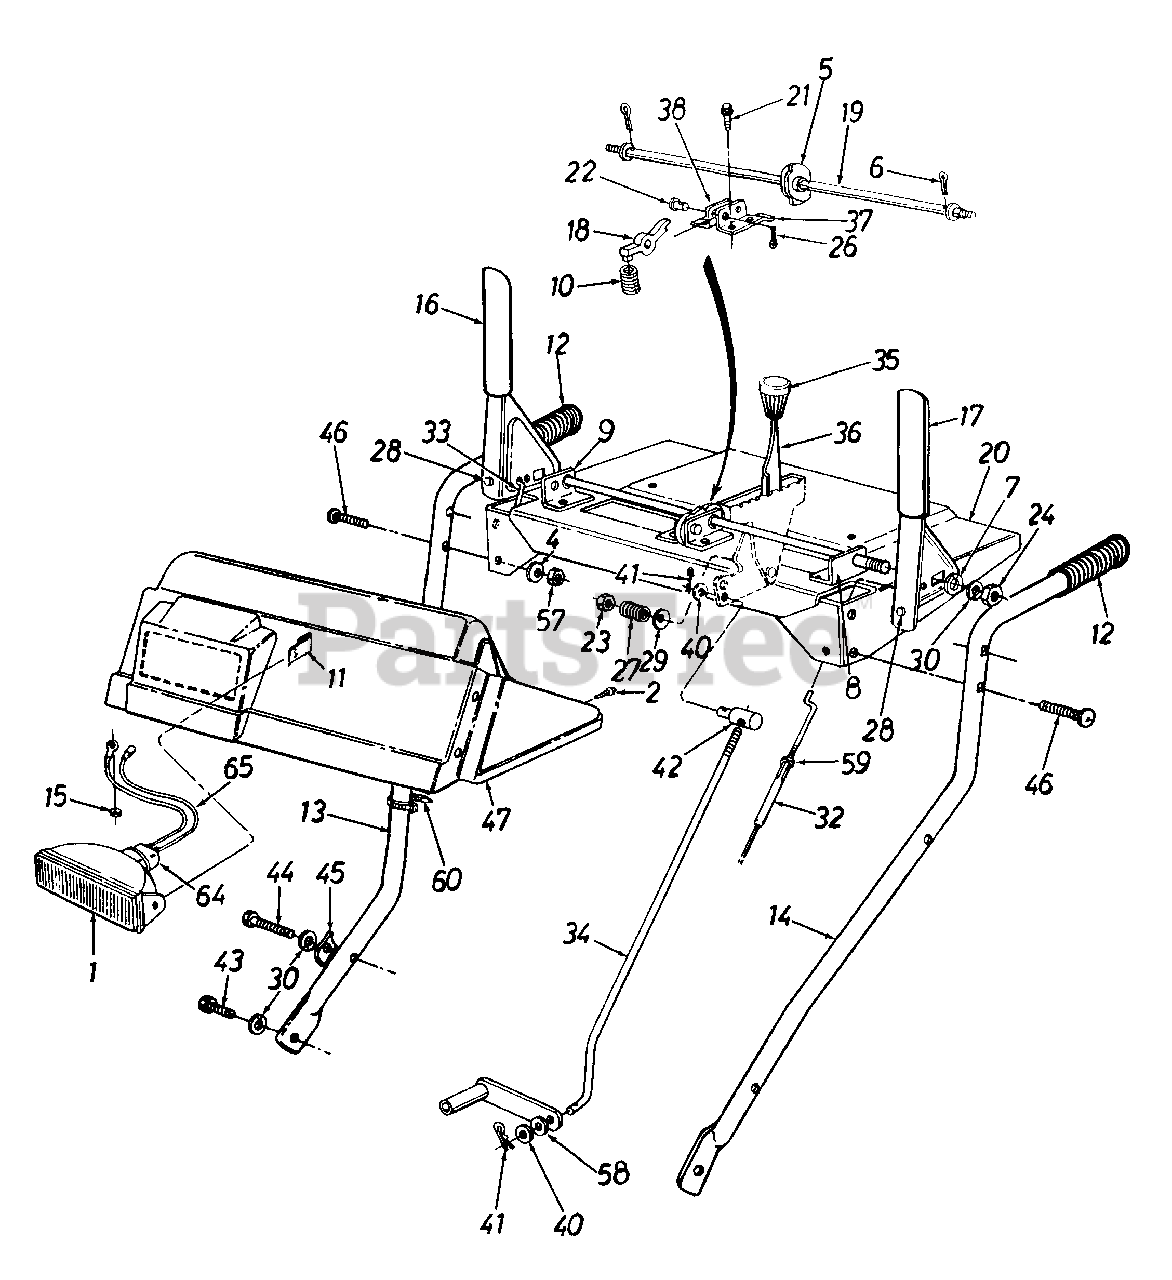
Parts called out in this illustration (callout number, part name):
1	Lamp Housing w/Lens
2	Truss Mach. B-Tap Scr. #10 x .5
4	BELL-Wash .325" I.D. x .88" O.D.
5	Cam Handle Lock
6	Cotter Pin 3/32" Dia. x .75" Lg.
7	Washer (Special) .72" O.D.
10	Compression Spring
11	Retaining Clip
13	Handle - R.H.
14	Handle - L.H.
15	Hex Sems Nut 1/4-20 Thd.
16	Engagement Handle - R.H.
17	Engagement Handle - L.H.
18	Pawl Handle Lock
19	Rod Cam
22	Clevis Pin .437" Dia. x .65" Lg.
23	Hex Ins. L-Nut 3/8-24 Thd.
24	Hex Nut 5/16-18 Thd.
26	Cotter Pin 3/32" Dia. x 1" Lg.
27	Compression Spring
28	Rubber Bumper
29	Bell-Wash .38" I.D. x .88" O.D.
30	L-Wash. 5/16" I.D.
32	Auger Clutch Cable
33	Drive Clutch Cable
34	Shift Rod
35	Shift Knob
36	Shift Handle
40	Fl-Wash .344" I D x .62" O.D.
41	Internal Cotter Pin 5/16" Dia.
42	Ferrule
43	Hex Bolt 5/16-18 x .62" Lg. (Special)
44	Hex Bolt 5/16-18 x 1 75" Lg. (Gr. 5)
45	Handle Tab
46	Curved Carr Bolt 5/16-18 x 1.5" Lg.
47	Handle Panel
57	Hex Nut 5/16-18 Thd.
58	Spr. Wash .32" I.D. x .62" O.D.
59	Hex Nut #10-24 Thd.
60	Cable Tie
64	Bulb
65	Wire Harness
